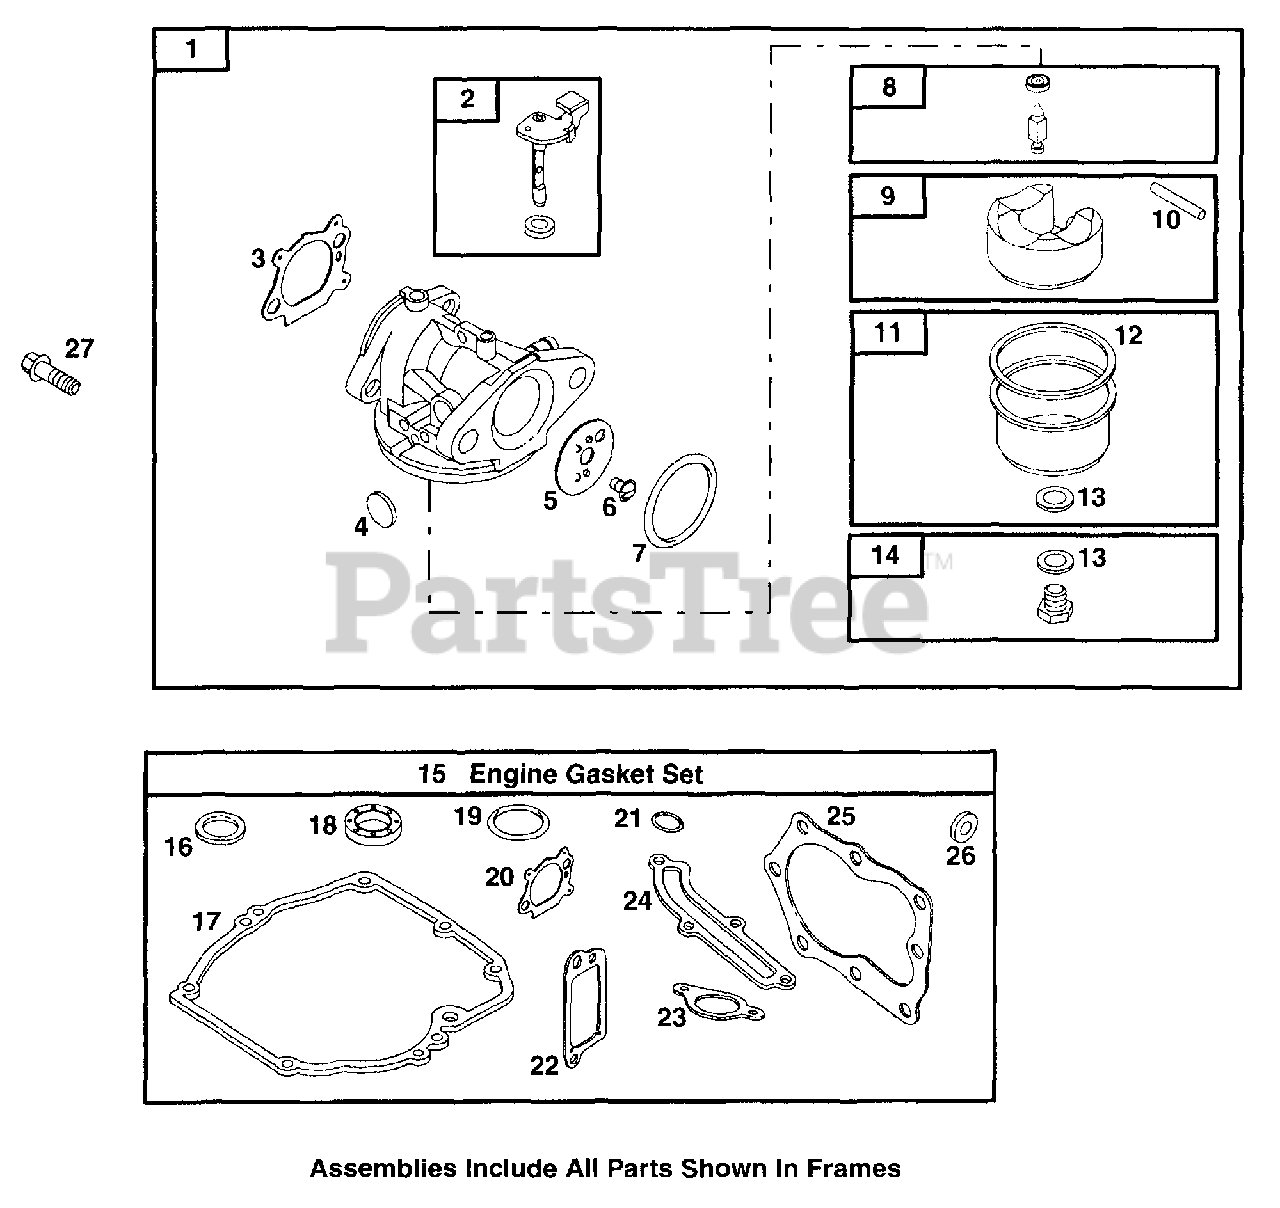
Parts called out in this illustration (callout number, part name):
1	Carburetor
2	Throttle Shaft
3	Air Cleaner Gasket
4	Welch Plug
5	Throttle Valve
6	Screw (Throttle Valve)
7	O-Ring Seal (Intake Manifold)
8	Needle/Seat Kit
9	Carburetor Float
10	Float Hinge Pin
11	Float Bowl
12	Float Bowl Gasket
13	Sealing Washer
14	Main Jet (Standard)
15	Engine Gasket Set
16	Oil Seal
17	Crankcase Gasket
18	Oil Seal
19	Dipstick/Tube Seal
20	Air Cleaner Gasket
21	Dipstick Tube Seal
22	Breather Gasket
23	Intake Gasket
24	Breather Passage Gasket
25	Cylinder Head Gasket
26	Spacer
27	Screw (Carburetor)
